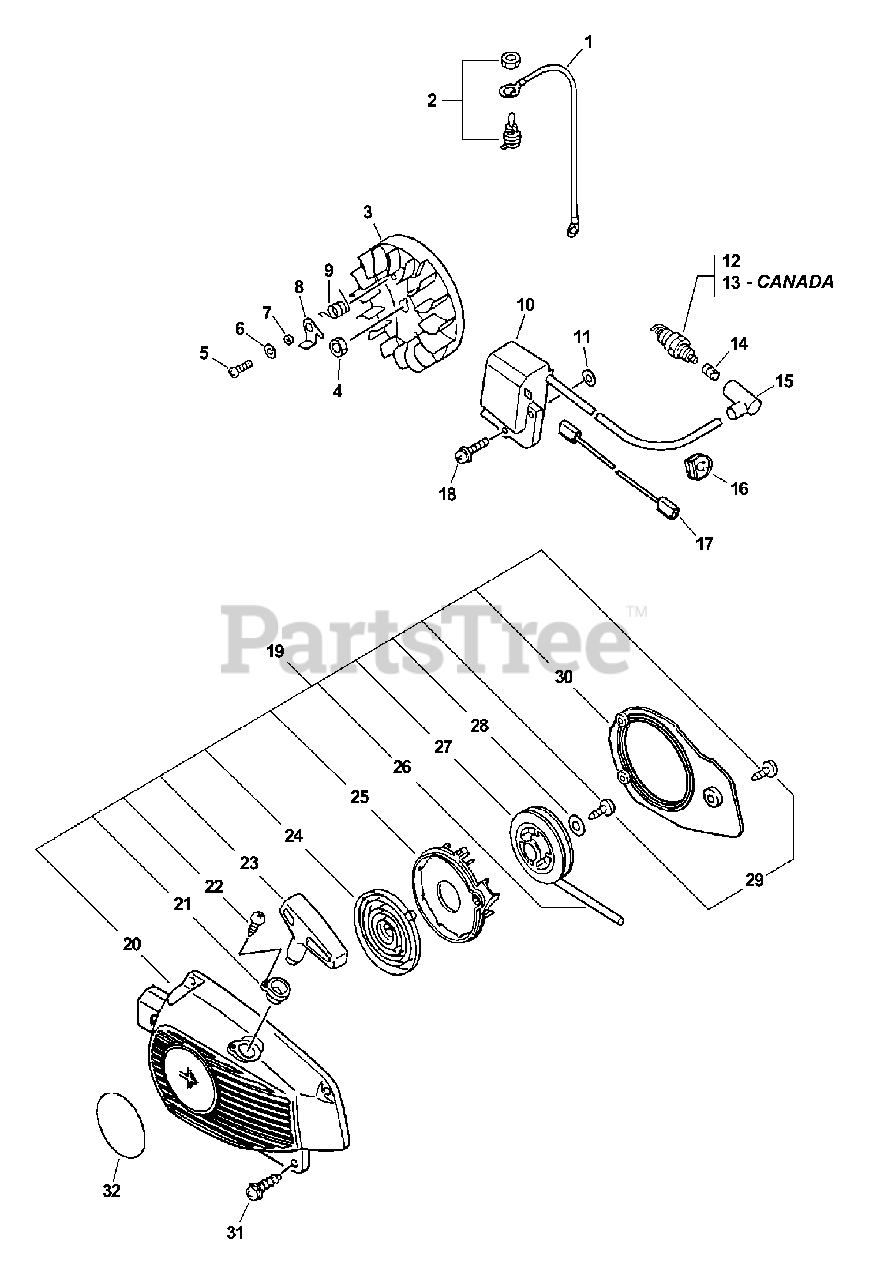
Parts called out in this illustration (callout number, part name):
1	LEAD - GROUND L= 100
2	SWITCH, ON-OFF
3	FLYWHEEL
4	NUT, FLANGE M8
5	SCREW 5×12
6	WASHER 5.5×12×0.8
7	SPACER 5.2×8×2.1
8	PAWL, STARTER
9	SPRING, TORSION
10	COIL, IGNITION
11	WASHER 5.2×12×3
12	SPARK PLUG - BPM8Y
13	SPARK PLUG - BPMR8Y
14	TERMINAL, SPARK PLUG
15	CAP, SPARK PLUG
17	LEAD - IGNITION L= 95
18	SCREW 5×22
19	STARTER ASSY
20	CASE, STARTER
21	GUIDE, ROPE
22	SCREW 3×14
23	GRIP, STARTER
24	SPRING, RECOIL
25	PLATE, STARTER
26	ROPE, STARTER 3.0×850
27	REEL, ROPE
28	WASHER 4.1×15.5×1T
29	SCREW 4×14
31	SCREW 4×16
32	LABEL, ECHO
